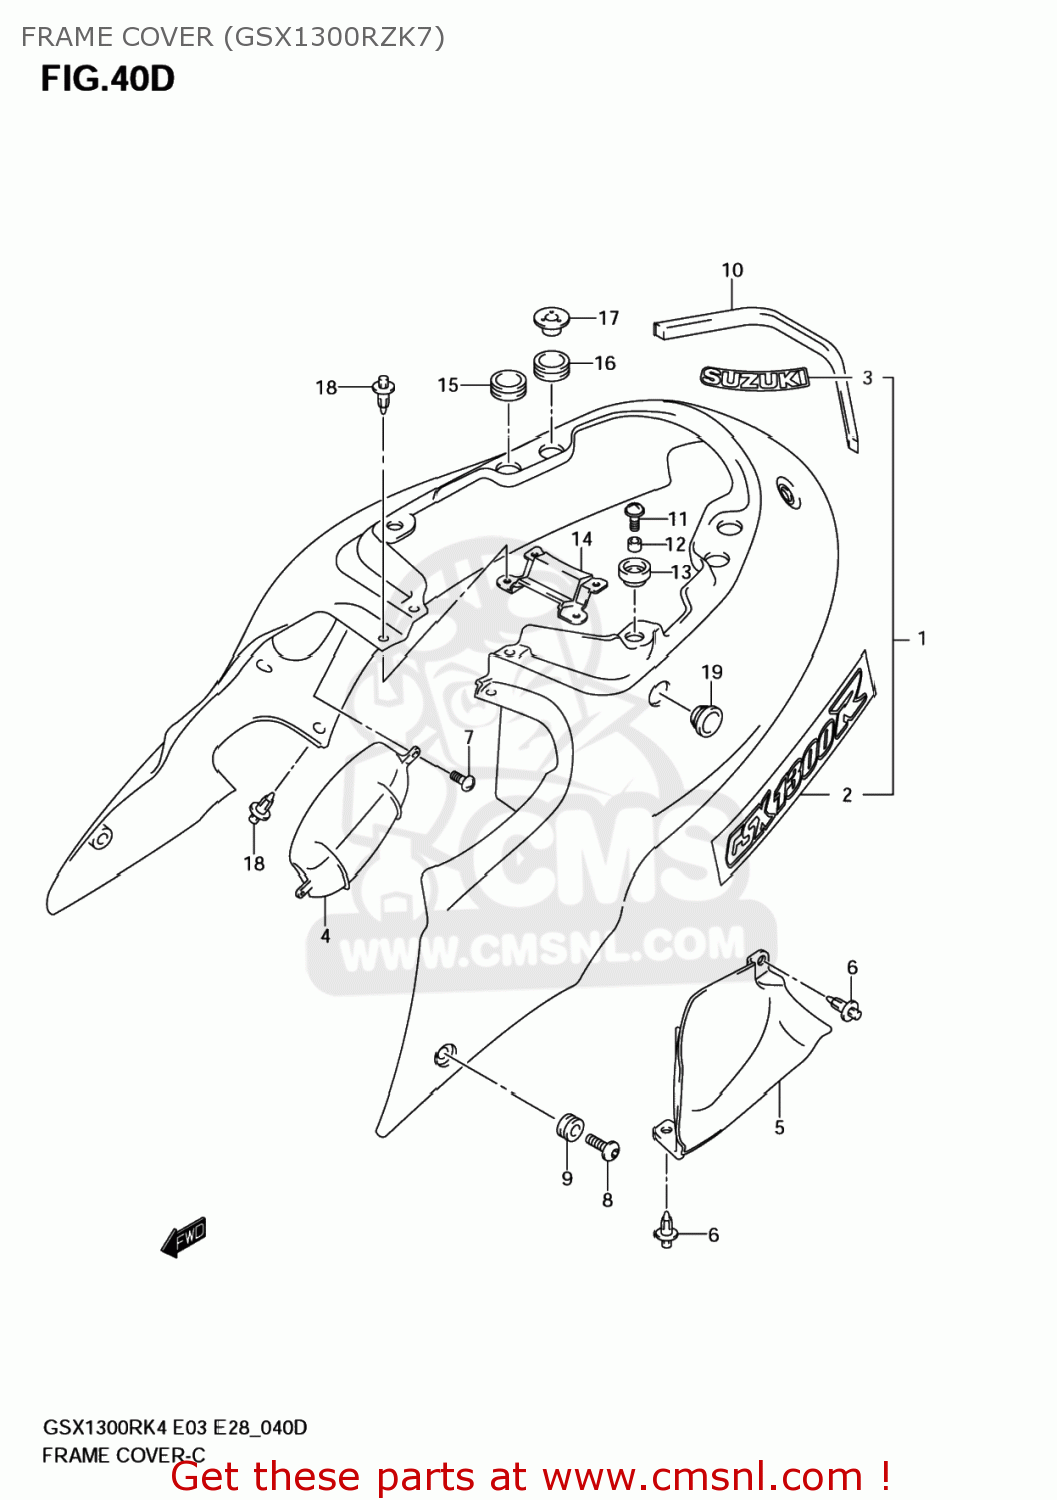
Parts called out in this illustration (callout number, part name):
1	COVER,FRAME(RED)
2	EMBLEM,FRAME COVER
3	EMBLEM,SUZUKI
4	CAP,FRAME COVER HOLE,R
5	CAP,FRAME COVER HOLE,L
6	CLIP(BLACK)
7	SCREW
8	SCREW(6X20)
9	CUSHION
10	CUSHION,FRAME COVER UPR
11	SCREW(6X20)
12	SPACER(6.5X10X11)
13	CUSHION
14	COVER,FRAME CTR
15	CUSHION,FRAME COVER UPR RR
16	CUSHION,FRAME COVER UPR RR RR
17	WASHER,FRAME C
18	CLIP(BLACK)
19	CUSHION,FRAME COVER CTR
